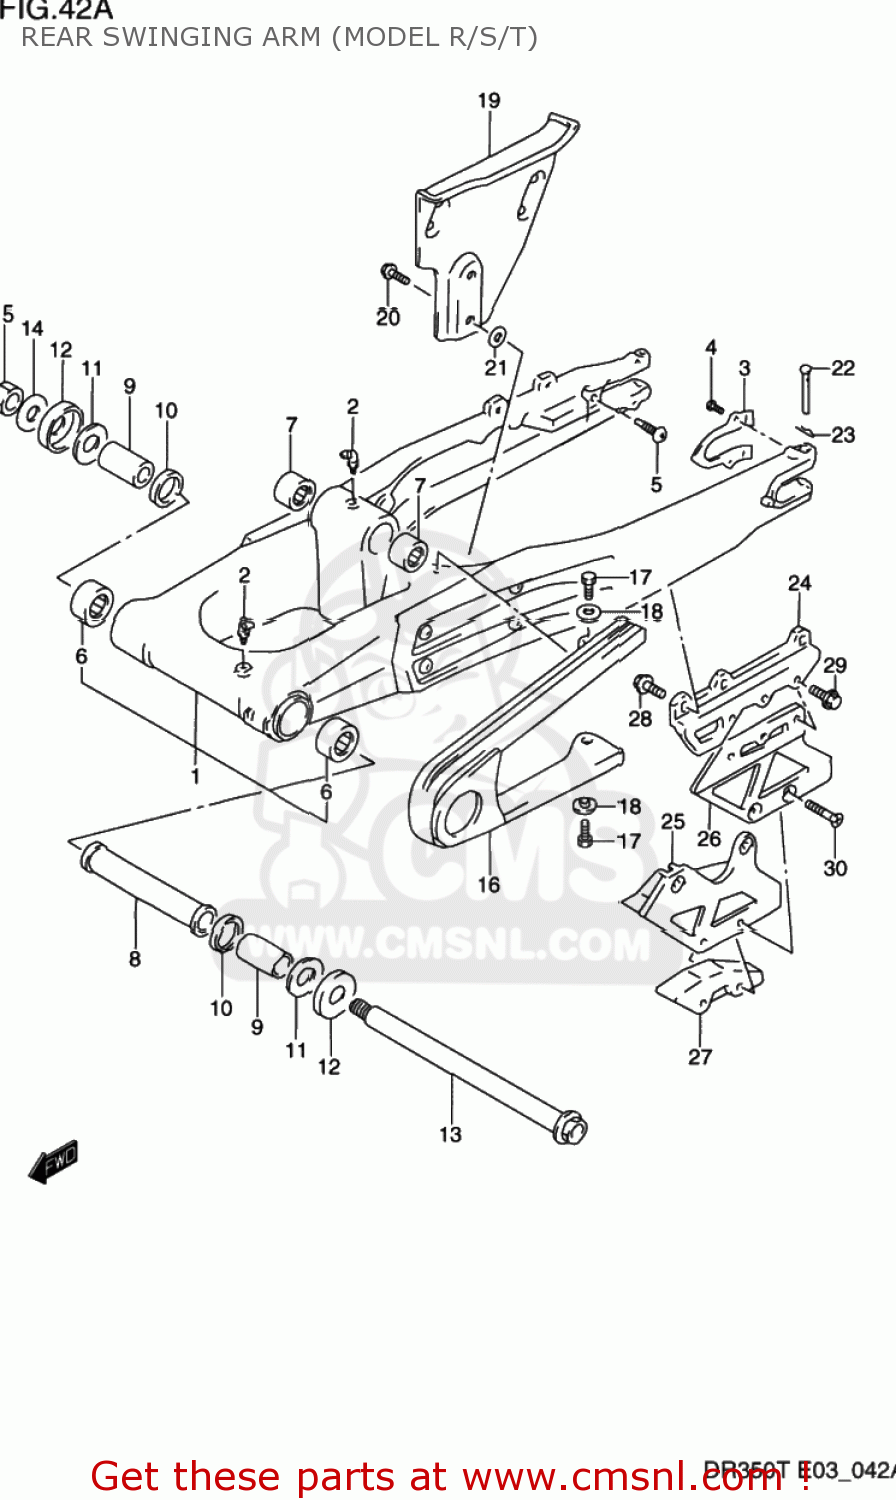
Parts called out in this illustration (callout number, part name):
1	SWINGINGARM ASSY,RR
2	NIPPLE,GREASE
3	PLATE,SWING ARM RR
4	SCREW (5X8)
5	SCREW (M10X21)
6	BEARING(22X29X30)
7	BEARING(20X27X23.5)
8	SPACER,SWING ARM PIVOT,CENTER
9	SPACER,SWGARM PIVOT BRG
10	SEAL,OIL(22X29X4)
11	WASHER
12	COVER,SWINGINGARM PIVOT
13	SHAFT,SWINGING ARM PIVOT
14	WASHER, FIXED DRIVE FACE
15	NUT
16	BUFFER,CHAIN TOUCH DEFENSE
17	BOLT
18	WASHER
19	GUARD,CHAIN
20	BOLT
21	WASHER
22	PIN
23	CLIP
24	BRACKET,CHAIN GUIDE
25	GUIDE,CHAIN
26	PLATE,CHAIN GUIDE OUTER
27	DEFENSE,CHAIN GUIDE
28	BOLT
29	SCREW
30	SCREW(6X40)
